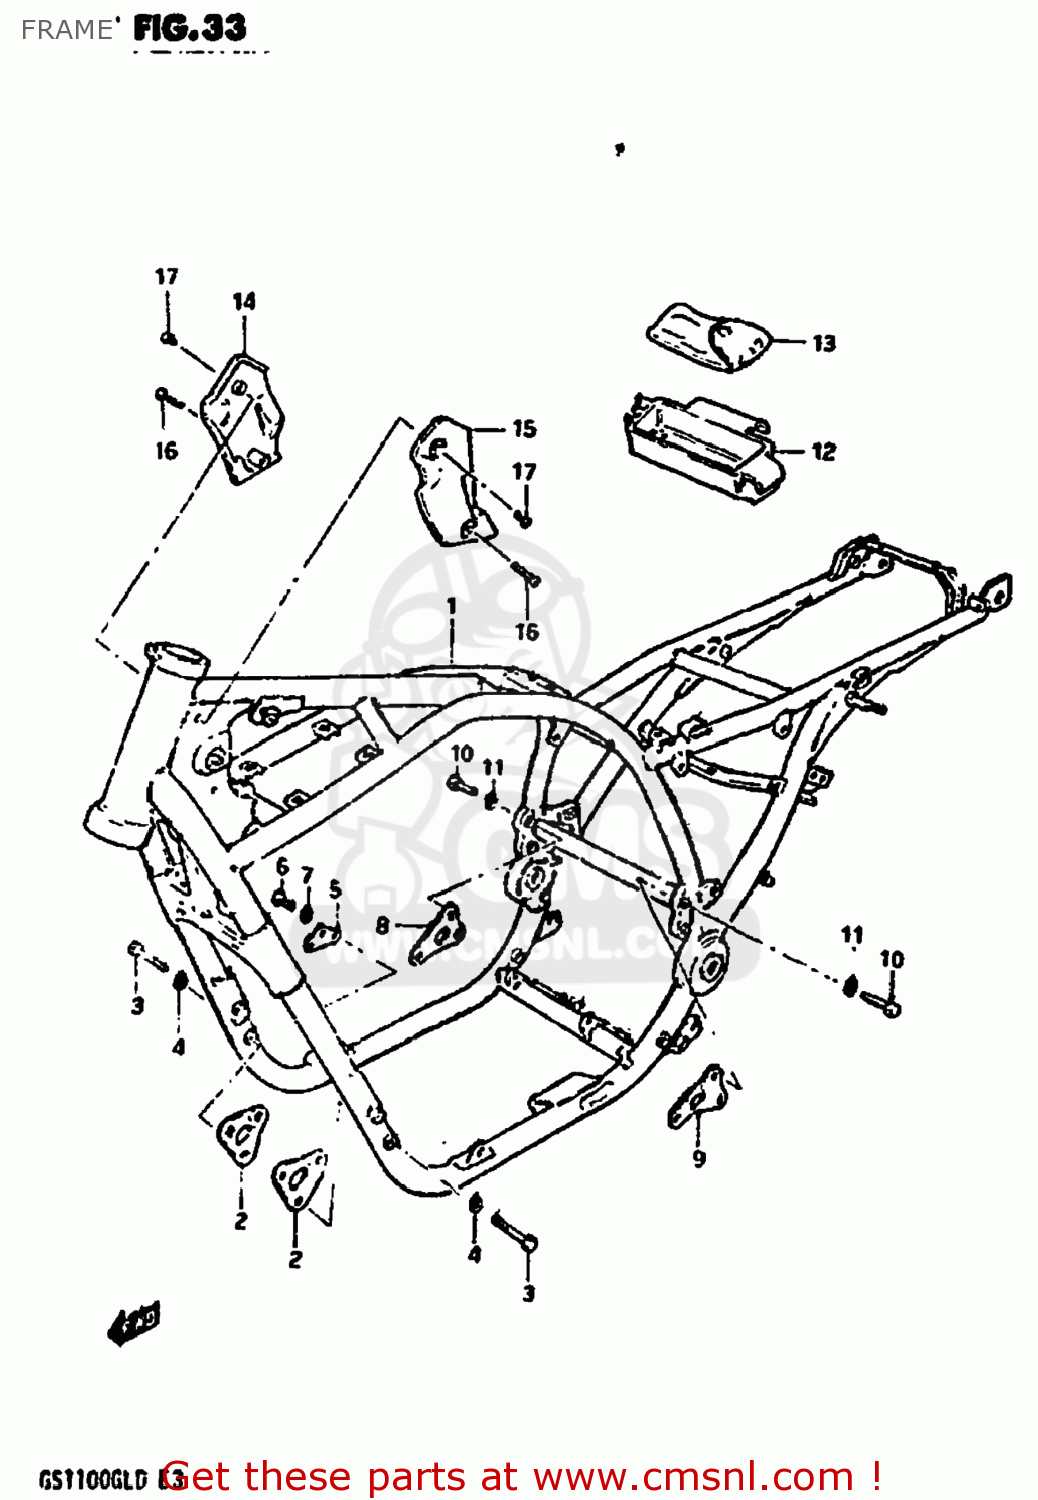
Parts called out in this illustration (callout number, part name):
1	FRAME
2	PLATE,ENGINE MOUNTING
3	BOLT
4	LOCK WASHER
5	PLATE,ENGINE MOUNTING
6	BOLT
7	LOCK WASHER
8	PLATE,ENGINE MOUNTING
9	PLATE,ENGINE MOUNTING
10	BOLT 8X40
11	LOCK WASHER
12	HOLDER,TOOL
13	TOOL SET
14	COVER,FRAME HEAD,RIGHT
15	COVER,FRAME HEAD,LEFT
16	SCREW, LOWER
17	(5X20) CROSS SCREW
